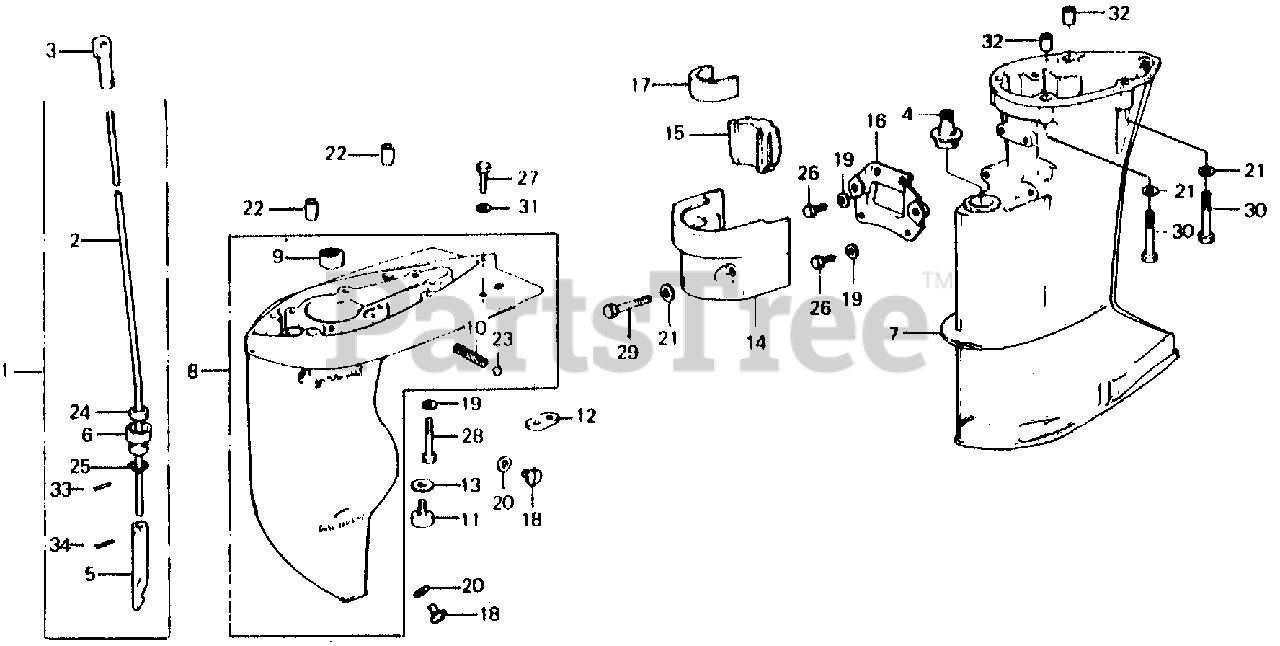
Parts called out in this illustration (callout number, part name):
1	ROD, GEARSHIFT (L)
2	ROD, GEARSHIFT (L)
3	JOINT, GEARSHIFT ROD
4	GROMMET, ROD (ARAI)
6	HOLDER, SEAL
7	CASE, EXTENSION *B9* (L) (ATLANTIS BLUE) (NOT AVAILABLE)
8	CASE, GEAR *B9* (ATLANTIS BLUE)
9	BEARING, NEEDLE (15X21X16)
10	SCREEN, WATER
11	METAL, ANODE (NOT AVAILABLE)
12	METAL, ANODE
13	RUBBER, INSULATE (NOT AVAILABLE)
14	HOUSING, SETTING (LOWER) *B9* (ATLANTIS BLUE) (NOT AVAILABLE)
15	RUBBER A, MOUNTING (LOWER)
16	PLATE, MOUNTING (LOWER)
17	RUBBER B, MOUNTING (LOWER)
18	BOLT, OIL CHECK
19	WASHER, PLAIN (6MM)
20	WASHER, NYLON (8MM)
21	WASHER, PLAIN (8MM)
22	PIN, DOWEL (8X10) (NOT AVAILABLE)
23	PLUG, SEALING (10MM)
24	SEAL, WATER (6MM)
25	O-RING (13.8X2.5)
26	BOLT, HEX. (6X12)
27	BOLT, HEX. (6X16)
28	BOLT, HEX. (6X40)
29	BOLT, HEX. (8X40)
30	BOLT, HEX. (8X50)
31	WASHER, PLAIN (6MM)
32	PIN A, DOWEL (10X14)
33	PIN, SPRING (2.5X12)
34	ROLLER (2.5X11.8)
